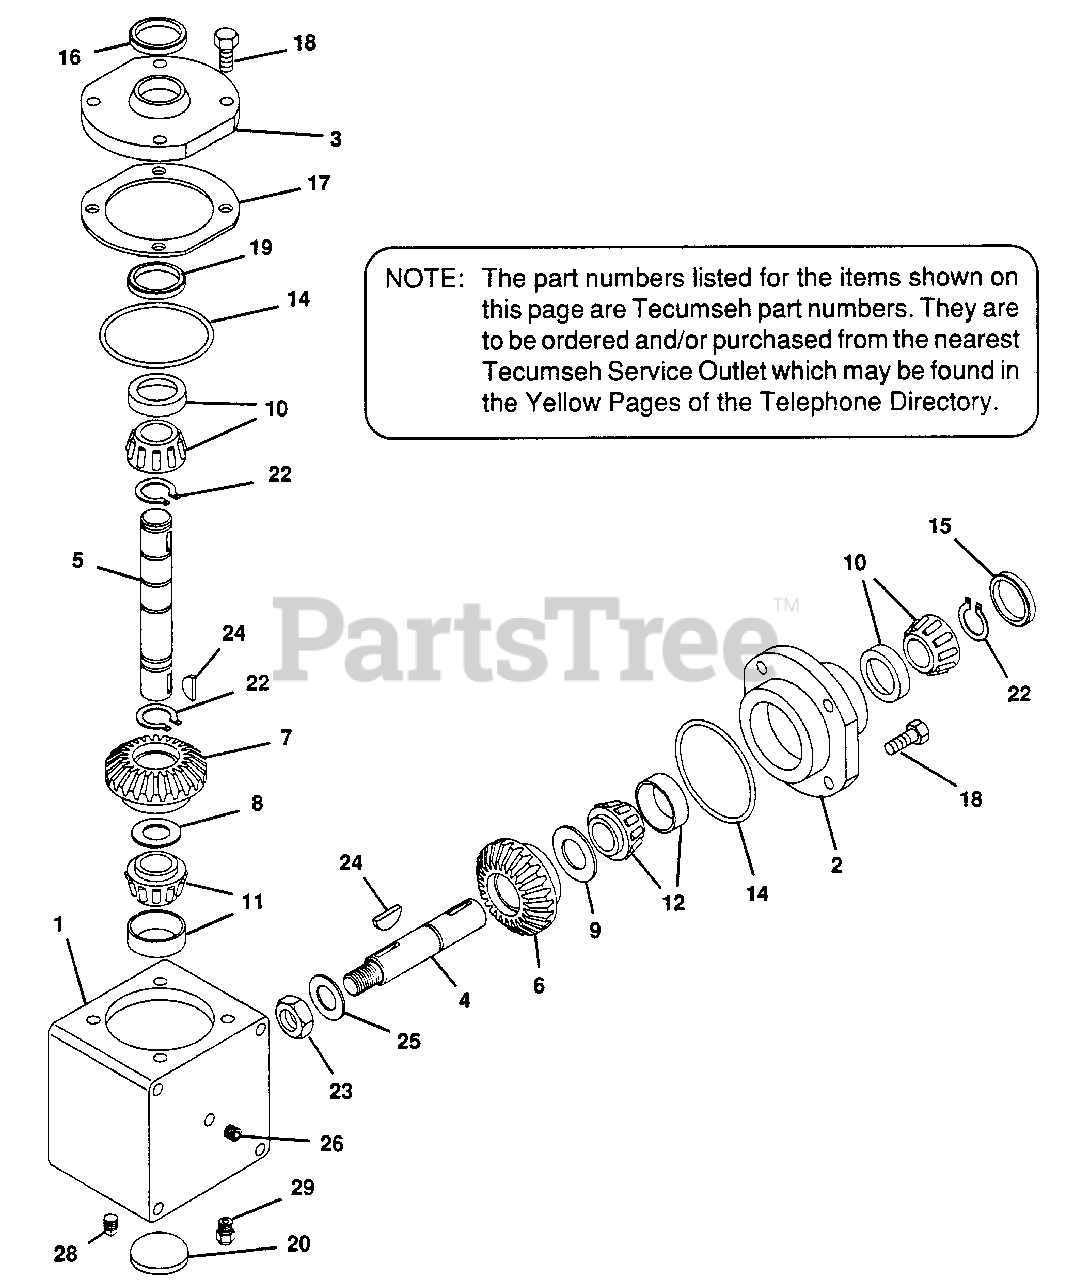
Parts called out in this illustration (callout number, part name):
1	HOUSING, RIGHT ANGLE DRIVE
2	CAP, RETAINER
3	CAP, RETAINER
4	SHAFT, INPUT (5.38" LONG)
5	SHAFT, OUTPUT (7.89" LONG)
6	GEAR, SPIRAL BEVEL (25 TEETH)
7	GEAR, SPIRAL BEVEL (26 TEETH)
8	SHIM (1-1/2" O.D. X 1-1/64" I.D.X.002 THICK)
9	SHIM (2.000" O.D.X1.531"I.D.X.002 THICK)
10	BEARING & CUP ASSY
11	BEARING & CUP ASSY
12	BEARING & CUP ASSY.
14	"O" RING
15	SEAL, OIL
16	SEAL, OIL
17	SHIM,CAP RETAINER
18	SCREW, HEX HEAD, SEMS, 5/16-18X1
19	RING, LOAD
22	RING, RETAINING
23	JAM NUT, 3/4-16
24	KEY, WOODRUFF
25	WASHER, FLAT
26	PLUG, PIPE 1/4-18
28	PLUG, PIPE 1/8-27
29	VALVE, RELIEF
